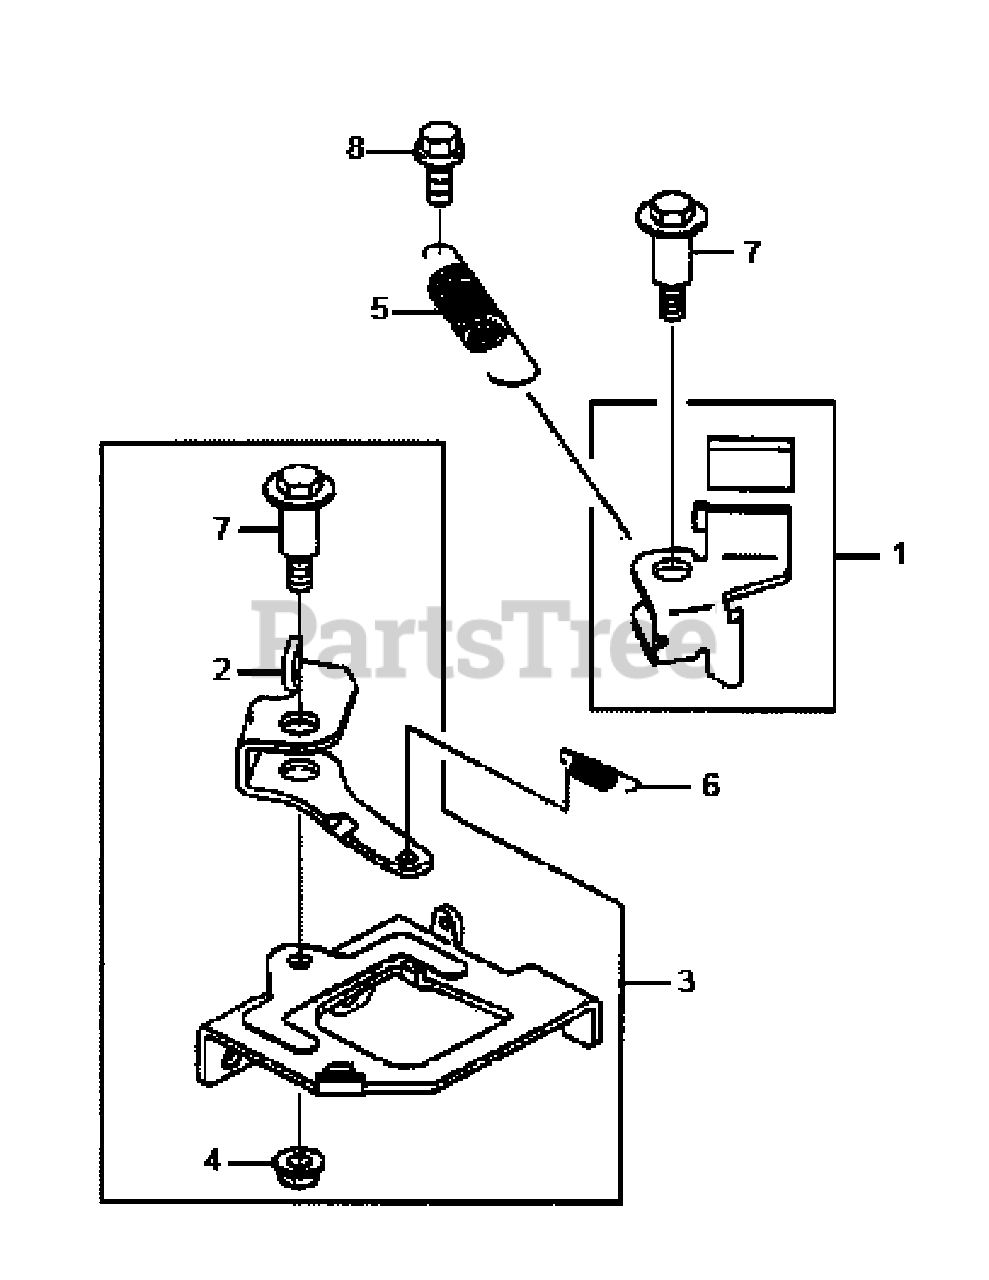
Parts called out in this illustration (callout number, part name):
1	Lever
3	Brake Panel Assy.
4	Nut
6	Spring
8	Flanged Bolt
